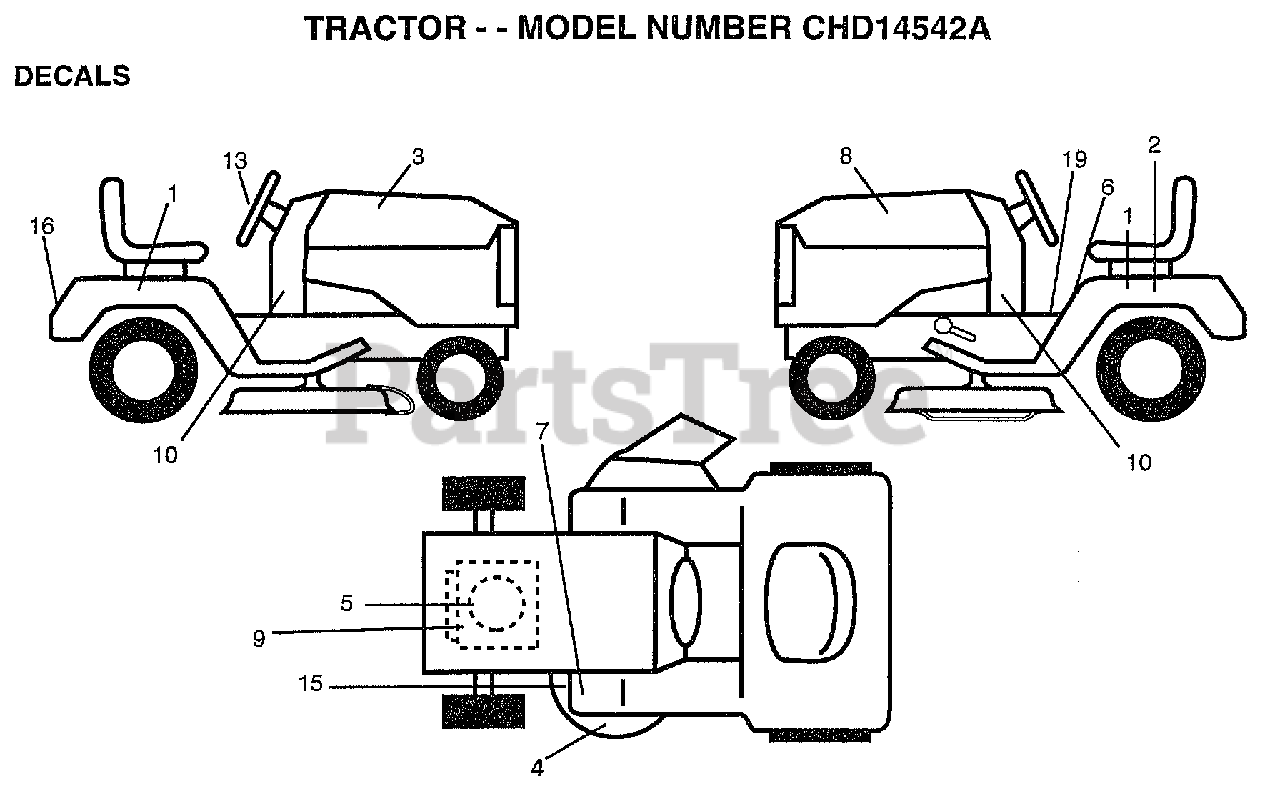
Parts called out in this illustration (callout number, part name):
1	DECAL.FENDER.SD.LAWN
2	DECAL.BATRY.3-3908
3	DECAL HOOD RH
4	"DECAL DECK,MULCH"
5	DECAL.ENGINE
6	DECAL.CAUT.ENG/FR
7	DECAL T
8	DECAL HOOD LH
9	DECAL.REPLACEMENT.ENG
10	DECAL DASH PNL
13	"DECAL WHEEL,STEER"
15	"DECAL-SCHEM,BELT"
16	"DECAL FENDER,LOGO"
19	"DECAL.OPER,SDL"
